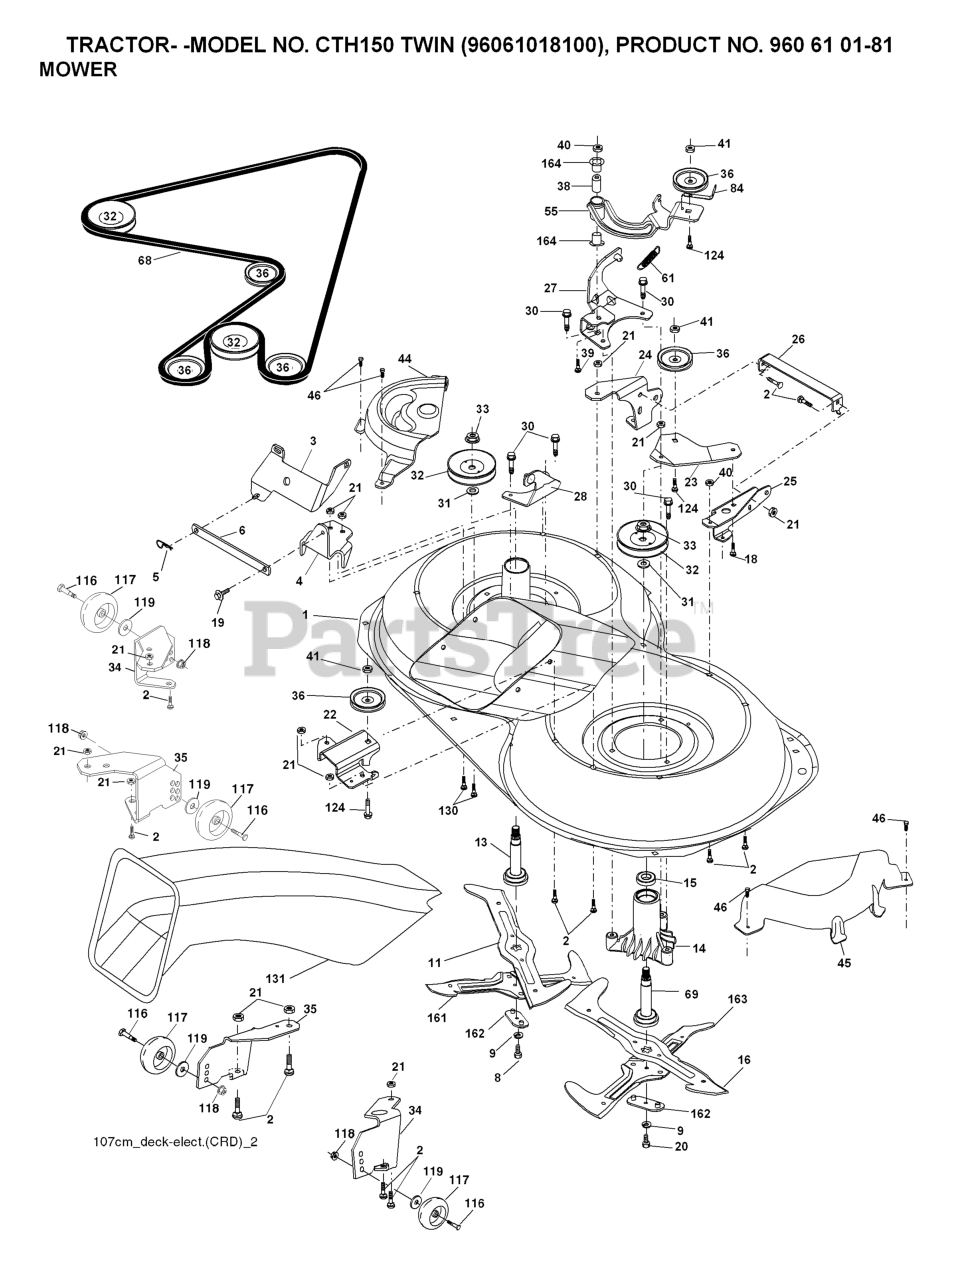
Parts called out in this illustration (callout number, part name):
1	Housing Asm. Mower 107 CRD
2	RP BOLT 5/16-18 X3/4 ZN/YEL GR
5	RETAINER-SPRNG RB
6	BAR.SWAY.92.CRD
8	BOLT.3/8-24X1.25 GR8
9	LOCKWASHER
11	BLADE.3N1.LH.CRD
13	SHAFT ASM VENT
14	HOUSING.MANDREL.VENTED (MACHD)
16	BLADE.3N1.RH.CRD
19	BOLT SHD 5/16-18
20	BOLT.3/8-24X1.25GR8. LHTHRD
21	LOCKNUT
22	BRACKET.IDLER.RR.107.CRD
25	BRACKET RF
26	SUPPORT
28	BRACKET
30	SCREW, WASHER HEAD
31	WASHER.SPACER.MANDREL
32	PULLEY.MANDREL.4.80 PD.2006
33	NUT.FLANGE.LOCK.TOP
34	BRACKET
35	BRACKET
36	PULLEY.IDLER.4.25
41	NUT LOCK FLG 3/8-16 UNC
45	COVER.MANDREL.RH.CRD
46	SCREW.1/4-20X5/8
55	ARM.IDLER.107.CRD
61	SPRING
68	HEX-BELT 107 MOWER
69	SHAFT.ASM.W/LWR.BRG.RH.THREAD
84	KEEPER, BELT IDLER
116	BOLT.SHOULDER.3/8-16X3-5/8.
117	RP WHEEL. GUAGE RALLY
118	NUT LOCK FLG 3/8-16 UNC
119	WASHER
124	BOLT.3/8-16X1.50
130	BOLT.CARR.SQNK.5/16-18UNC.X3/4
131	CHUTE BAGGER
163	BLADE.CROSS.RH.CRD.107
164	BRNG T
